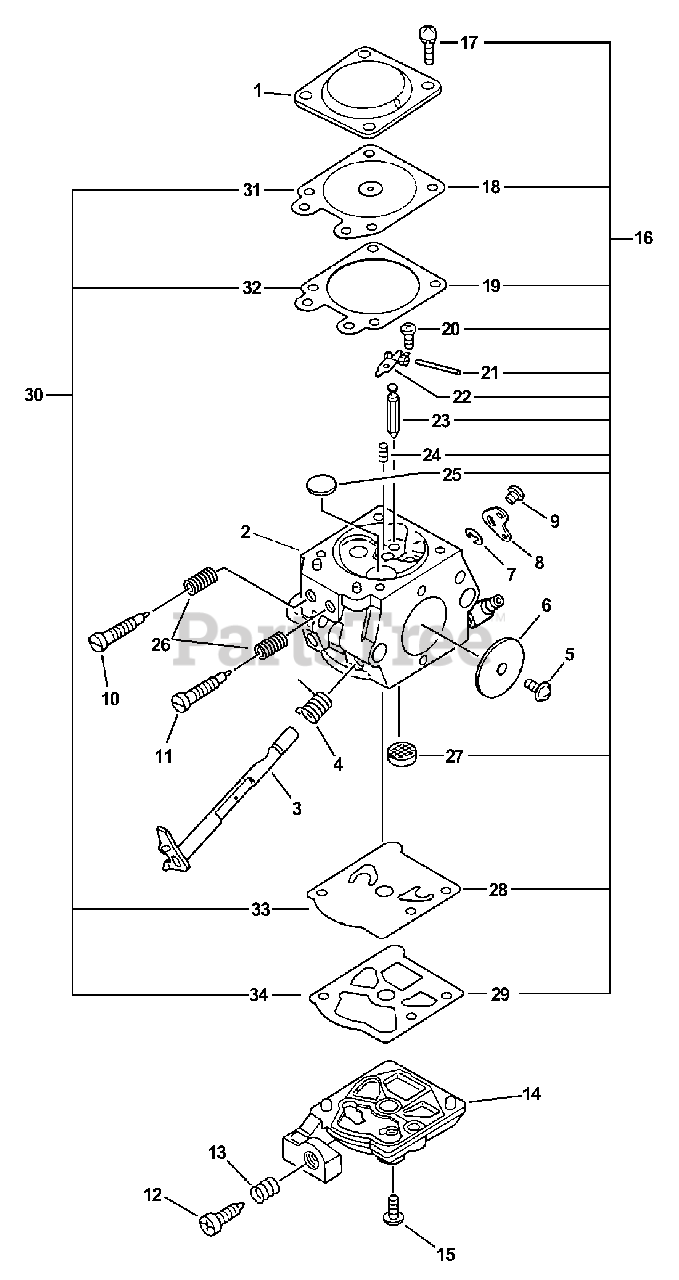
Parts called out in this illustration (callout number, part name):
1	COVER, METERING
2	BODY, CARBURETOR
3	SHAFT, THROTTLE
4	SPRING, THROTTLE RETURN
6	VALVE, THROTTLE
7	RING, RETAINING
8	LEVER, THROTTLE
9	LEVER, THROTTLE
10	NEEDLE - HIGH SPEED
11	NEEDLE - LOW SPEED
12	SCREW, IDLE ADJUST
13	SPRING, IDLE ADJUST
14	COVER, PUMP
15	SCREW, PUMP COVER
16	REPAIR KIT
17	SCREW, METERING COVER
18	DIAPHRAGM, METERING
19	GASKET, METERING
20	SCREW, METERING LEVER PIN
21	PIN, METERING LEVER
22	LEVER, METERING
23	VALVE, INLET NEEDLE
24	SPRING, METERING LEVER
25	PLUG, WELCH
26	SPRING
27	STRAINER
28	DIAPHRAGM, PUMP
29	GASKET, PUMP
30	DIAPHRAGM/GASKET KIT
31	DIAPHRAGM, METERING
32	GASKET, METERING
33	DIAPHRAGM, PUMP
34	GASKET, PUMP
